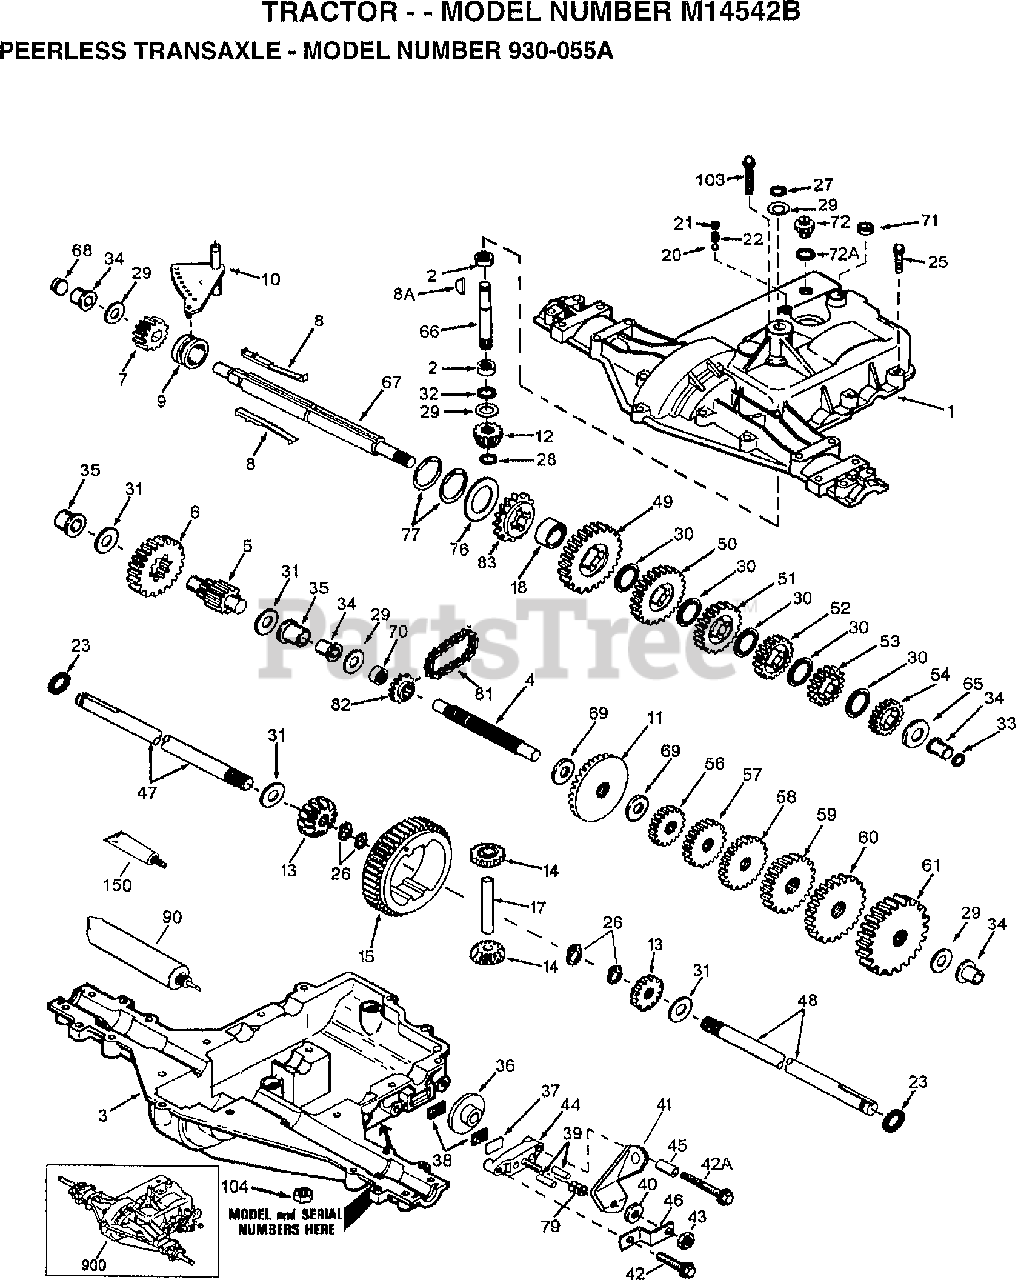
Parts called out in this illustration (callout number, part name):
1	TRANSAXLE COVER
2	BEARING, NEEDLE
3	TRANSAXLE CASE
4	SHAFT, COUNTER
5	OUTPUT SHAFT AND PINION
6	GEAR, OUTPUT
7	GEAR, SPUR, 15 TEETH
8A	KEY, WOODRUFF
9	COLLAR, SHIFTER
10	ROD & FORK ASSY, SHIFT
11	GEAR, BEVEL, 42 TEETH
12	BEVEL PINION, INPUT
13	GEAR, BEVEL
14	GEAR, BEVEL, PINION
18	SPACER, NEUTRAL
20	BALL STEEL, 5/16" DIA.
21	SCREW, 3/8-16 X 3/8"
25	SCREW, 1/4-20 X 1-1/4
26	RING RETAINER
27	RING, RETAINER
28	RETAINING RING
29	WASHER THRUST
30	WASHER THRUST
33	SEAL, SQUARE CUT
34	BUSHING, FLANGED
35	BUSHING, FLANGED
36	DISK, BRAKE
37	PLATE BRAKE PAD
41	BRAKE LEVER
42	SCREW, 1/4-20 X 1-1/4
42A	SCREW, 1/4-20 X 2-1/4
43	LOCKNUT 5/16-24
44	HOLDER BRAKE PAD
46	BRKT BRAKE LEVER
49	GEAR, SPUR, 37 TEETH
50	GEAR, SPUR, 35 TEETH
51	GEAR, SPUR, 30 TEETH
52	GEAR, SPUR, 25 TEETH
53	GEAR, SPUR, 22 TEETH
54	GEAR, SPUR, 19T
56	GEAR, SPUR, 12 TEETH
57	GEAR, SPUR, 15 TEETH
58	GEAR, SPUR, 20 TEETH
59	GEAR, SPUR, 25 TEETH
60	GEAR, SPUR, 28 TEETH
61	GEAR, SPUR, 31 TEETH
65	WASHER, THRUST
66	SHAFT, INPUT
67	SHAFT, BRAKE, 4 KEYED
69	WASHER THRUST
71	SEAL SQUARE CUT
72	THREADED PLUG 9/16-18
76	WASHER, THRUST
77	INVERTED RETAINING RING
81	CHAIN, ROLLER
82	SPROCKET 9T
83	SPROCKET 18T (REV)
90	GREASE BENTONITE, 32 OZ.
150	GASKET ELIMINATOR
900	REPLACEMENT TRANSAXLE
